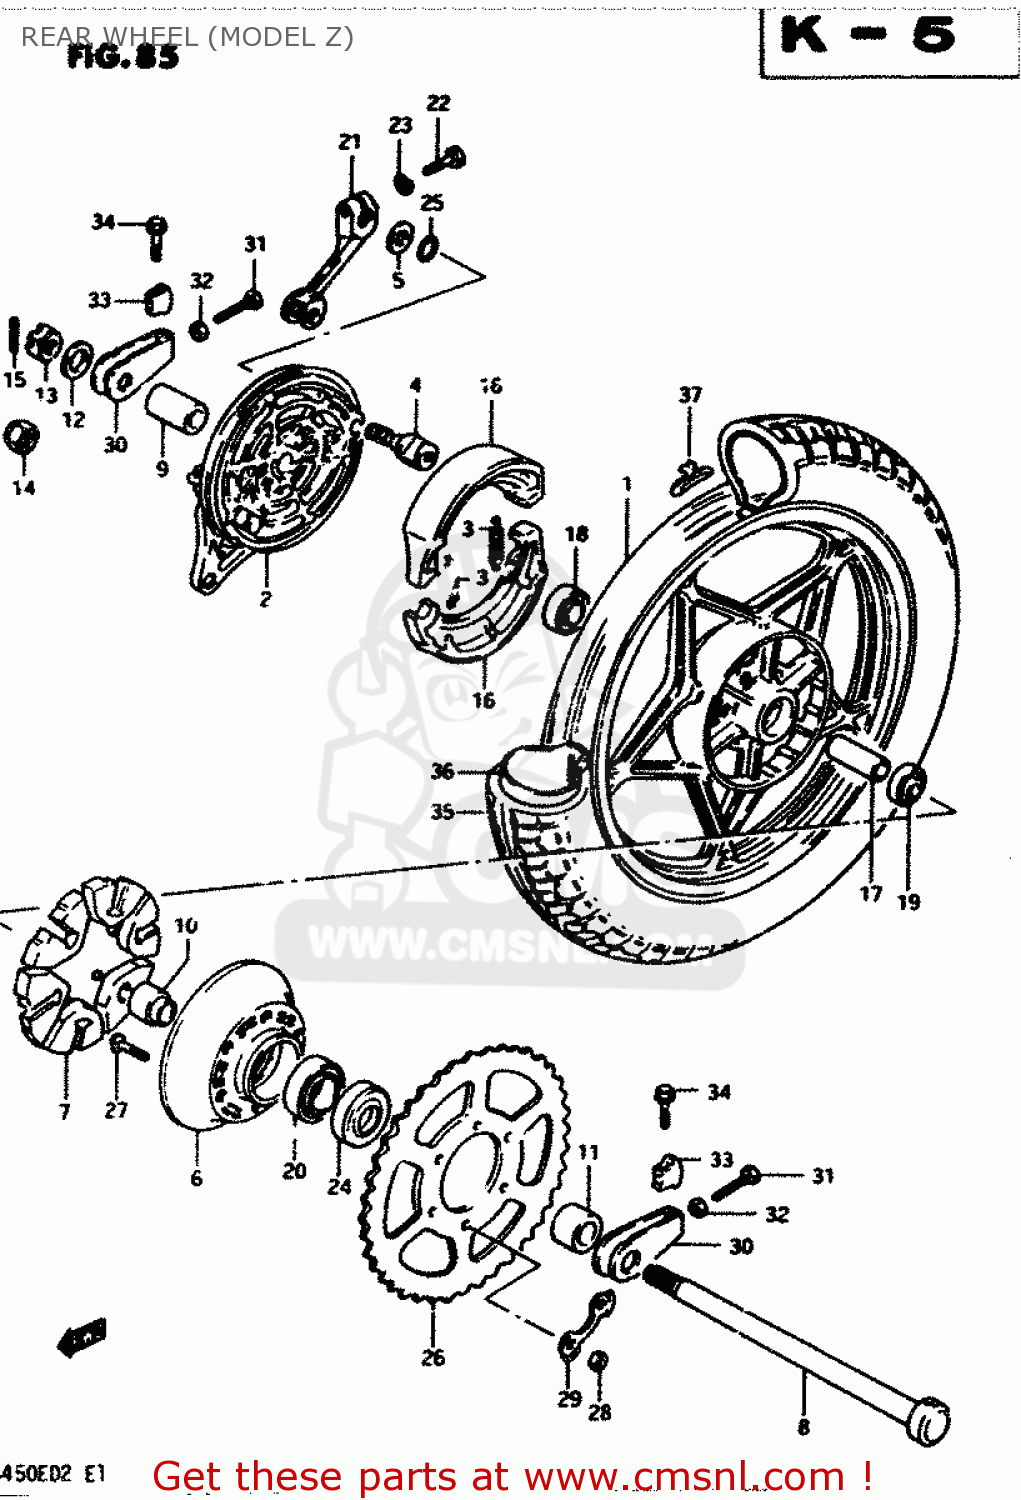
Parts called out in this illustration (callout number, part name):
1	CASTING WHEEL,REAR 1.85-
2	PANEL,REAR HUB
3	SPRING,BRAKE SHOE
4	CAM,FRONT BRAKE
5	WASHER (15X24X1.6)
6	DRUM,REAR SPROCKET MOUNT
7	ABSORBER,RR HUB SHOCK
8	AXLE,REAR
9	SPACER(17.5X28X44.8)
10	SPACER,REAR HUB BEARING
11	SPACER(17X30.5X22.3)
12	WASHER (17X30X3.2)
13	NUT
14	NUT
15	PIN,COTTER
16	SHOE,BRAKE
17	SPACER (17.6X24X57)
18	BEARING
19	BEARING
20	BEARING
21	LEVER,RR BRAKE CAM
22	BOLT
23	LOCK WASHER
24	SEAL,OIL(30.5X52X8)
25	O-RING,BOSS
26	SPROCKET,RR
27	BOLT
28	NUT
29	WASHER
30	ADJUSTER,CHAIN
31	BOLT 8X50
32	NUT
33	SUPPORTER,CHAIN ADJUST
34	BOLT
35	TIRE
36	TUBE ASSEMBLY,WHEEL,INNER
37	BALANCER,WHEEL
